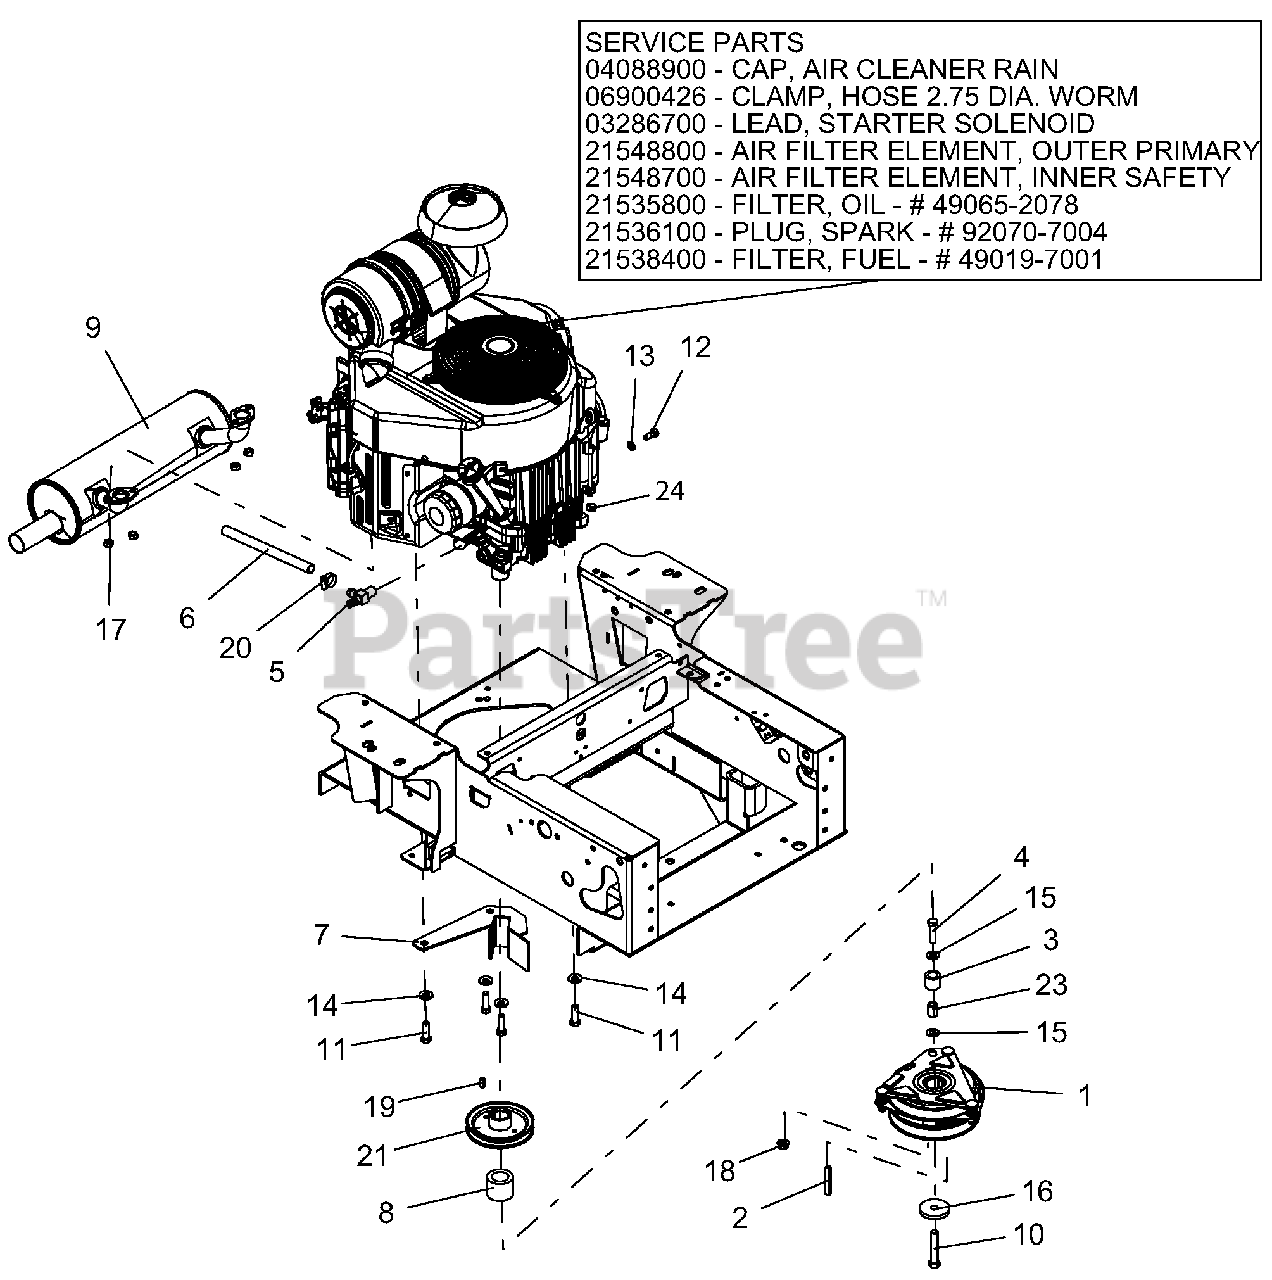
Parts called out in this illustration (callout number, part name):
1	CLUTCH, OGURA GT2.5-FE02
2	KEY, .25X.25X2.25
3	BUMPER, RUBBER .62 X 1.0 X .88 LG
4	BLT-HEX .38-16X1.50 GR5 YWZC
5	DRAIN, 1/2" OIL
6	TUBE, OIL DRAIN 8" CLEAR VINYL
7	WMT, 100I CLUTCH STOP - BLK
8	SPACER, 1.125 X 1.75 X 1.40
9	MUFFLER, KAWASAKI FX24/26 HP
10	BLT-HEX .44-20X2.50 GR5 EP80 YWZC
11	BLT-HEX .38-16X1.25 GR5 YWZC NYTORQ
12	@BLT-HEX M8-1.25X20 YWZC
13	WSHR-LK .31X.078 REG YWZC
14	WSHR, 3/8" SPRING DISC
15	WSHR-FL-STL.406X.812X.065 YWZ
16	WSHR-FL-STL .469X2.00X.25 YWZC
17	NUT-LK-TOP M8-1.25 YWZC
18	NUT, LK-TOP-FLG .38-16 YWZC
19	KEY-SQ .250X.250X.625
20	CLAMP, .88 DIA HOSE
21	PULLEY, 4.50 OD X 1.127 ENGINE-BLACK
23	BUSHING, SLV .407X.625X.813
24	CLAMP, FUEL LINE
